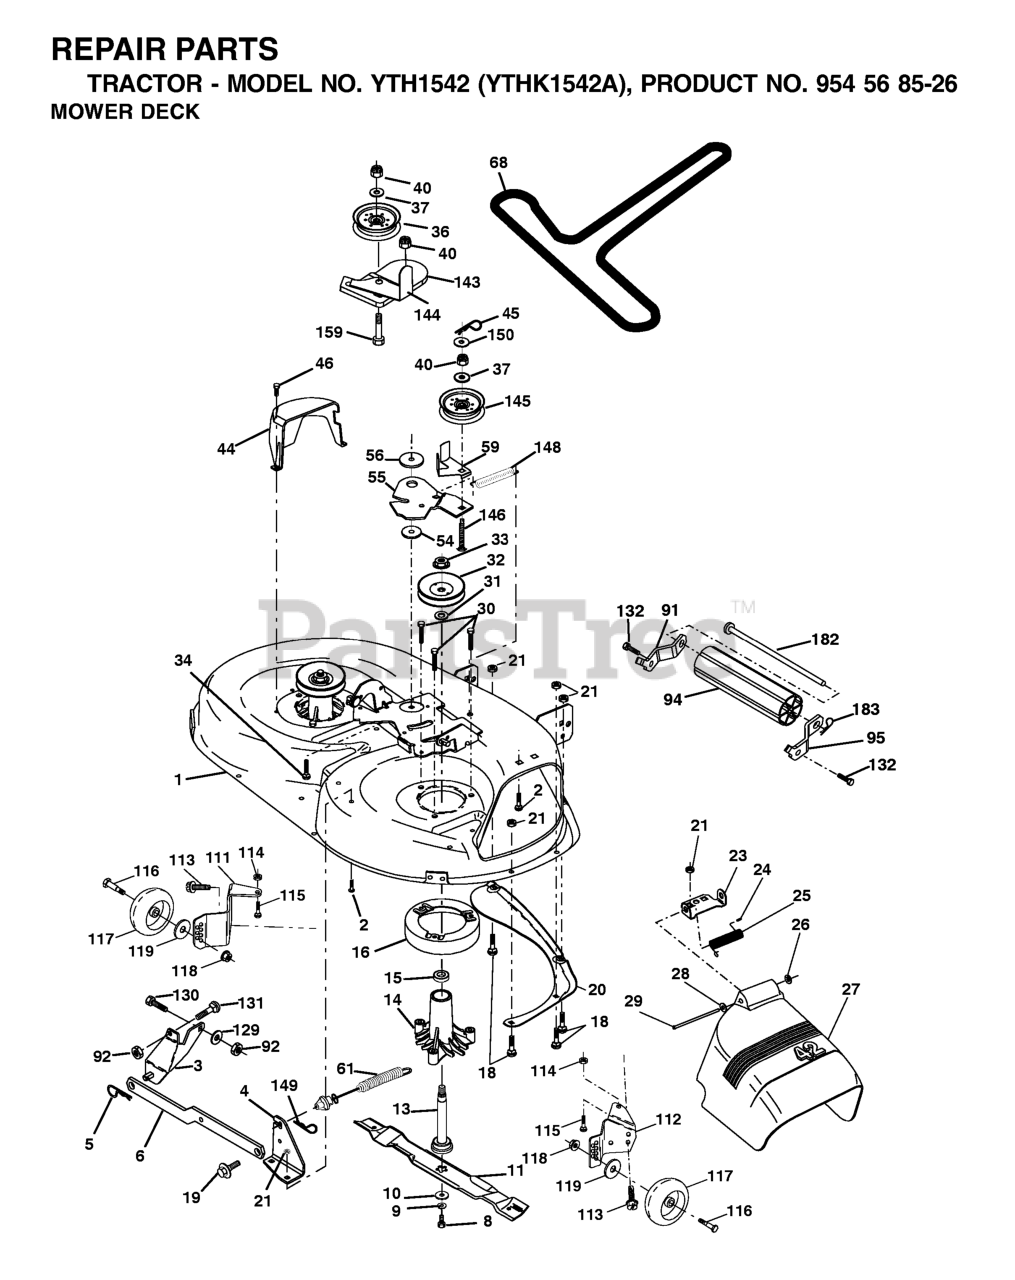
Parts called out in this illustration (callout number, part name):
1	42" DECK KIT
2	RP BOLT 5/16-18 X3/4 ZN/YEL GR
3	BRKT ASM SWAY BAR
4	BRACKET SWAY BAR 42" DECK
5	RETAINER-SPRNG RB
6	BAR SWAY DECK
8	BLADE BOLT
9	LOCKWASHER
10	WASHER.BLADE
11	Blade Mower 42" High Perf.
13	SHAFT ASM VENT
14	HOUSING.MANDREL.VENTED (MACHD)
16	STRIPPER.MANDREL.ROUND.BLACK
18	BOLT
19	BOLT SHD 5/16-18
20	BAFFLE.VORTEX
21	LOCKNUT
23	BRKT, DEFL. MOWER
24	CAP-SLEEVE LT
25	SPRING TORSION
26	NUT PUSH M
27	SHIELD DEFLECTOR
28	Washer 11/32 x 5/8 x 16 Ga SD
29	ROD.HINGE
30	SCREW, WASHER HEAD
31	WASHER
32	PULLEY MANDREL
33	NUT, FLG TOPLOCK 9/16"
36	PULLEY.IDLER.FLAT
37	WASHER
44	GUARD MANDREL LH BLACK
45	RETAINER M
46	SCREW.1/4-20X5/8
54	HARDENED WASHER
55	ARM IDLER 42" MOWER LT/YT
56	SPACER RETAINER
59	GUARD TUV IDLER
61	SPRING EXT ELEC CLUTCH
68	V-BELT PRIMARY 42"
91	BRACKET ASM NOSEROLLER LH
94	NOSE ROLLER
95	BRACKET ASM NOSEROLLER RH
111	BRACKET, WHEEL
112	BRACKET, WHEEL
113	Screw Tapping 3/8-16 x .625
114	NUT
115	BOLT.CARR.5/16-18X5/8.SHORT
116	BOLT, SHOULDER
117	WHEEL.GAUGE.STANDARD
118	LOCKNUT
119	WASHER.5/16.FLAT.STE.STD.
132	SCREW 3/8-16X3/4
143	BRACKET, ARM IDLER
144	KEEPER BELT 42" CLUTCH
145	PULLEY.IDLER.FLAT.PLATED
146	BOLT, CARRIAGE IDLER BLACK
148	IDLER RETURN SPRING
149	SPRING.RETAINER.YELLOW.ZINC
150	WASHER PM
159	BOLT
182	ROD ROLLER NOSE STANDARD
183	SPRING RETAINER
